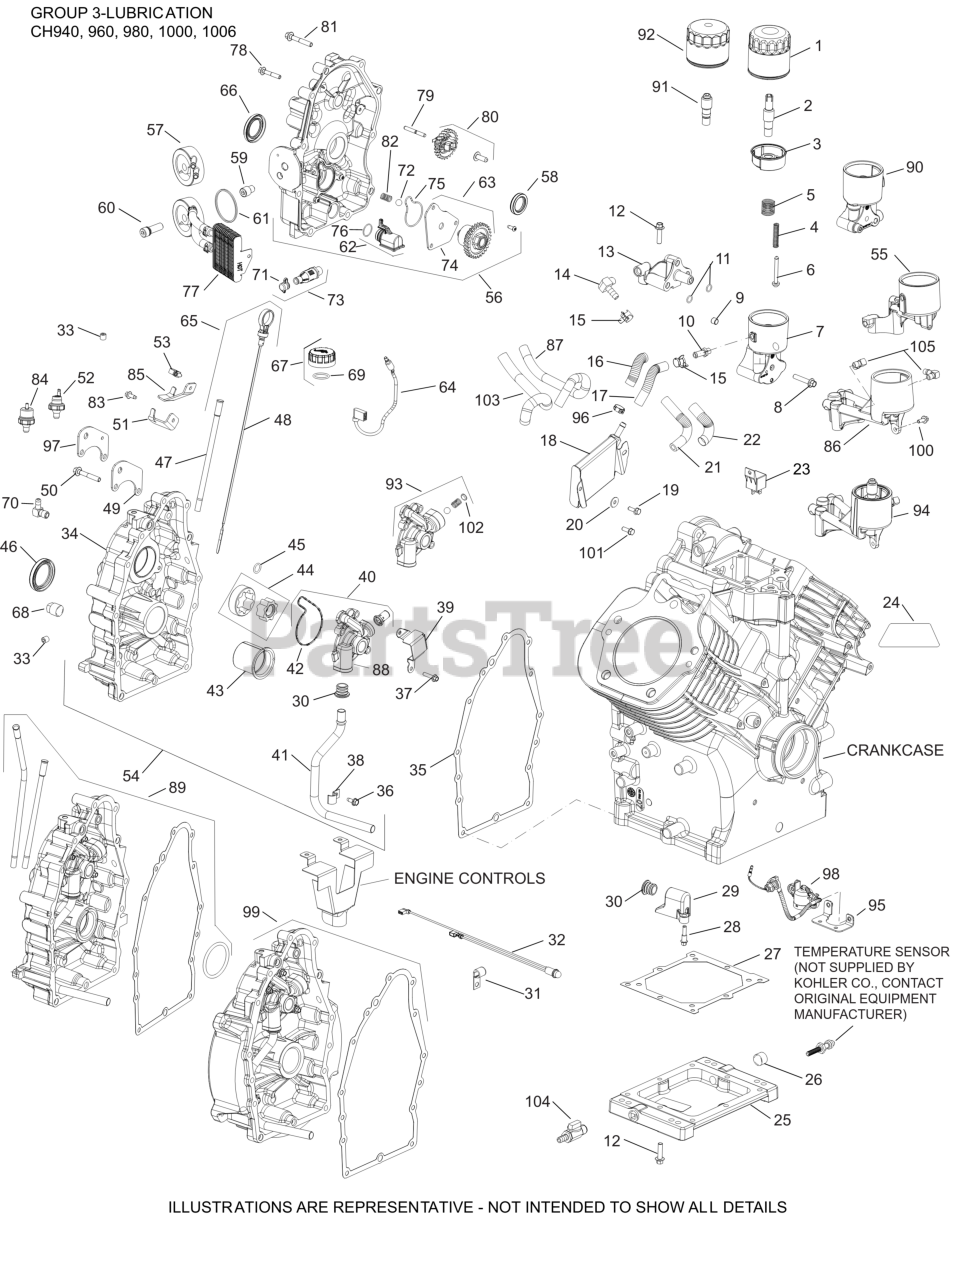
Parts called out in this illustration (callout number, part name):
1	OIL FILTER
3	CUP, OIL FILTER ASSEMBLY
4	SPRING, OIL FILTER VALVE
5	SPRING, OIL FILTER CUP
6	VALVE, OIL FILTER
11	O-RING, OIL PICK-UP
12	SCREW, FLG M8X1.25X30
15	SPRING CLAMP, HOSE
18	COOLER, OIL ASSEMBLY
20	WASHER, FLAT 1/4"
21	HOSE, OIL SUPPLY
22	SLEEVE, ANTI ABRASION-USE 25 431 12-S
25	OIL RESERVOIR
26	BUSHNG,REDCR 1/2"-1/8" NPT STL
27	GASKET, OIL RESERVOIR
28	SCREW, SHD THD FRM M6X.0X6.5
29	HOUSING, OIL PICK-UP ASSEMBLY
30	SEAL, PICK-UP TUBE
33	PLUG, CTSK PIPE 1/8"
35	GASKET, OIL PAN
36	SCREW, THREAD FORMING
37	SCREW, HEX FLANGE M6 X 1
41	TUBE, OIL PICK-UP
42	O-RING, OIL PUMP HOUSING
44	PUMP ASSEMBLY, OIL/GEROTOR
47	KIT, DIPSTICK TUBE
51	BRACKET, DIPSTICK TUBE
52	SWITCH, OIL PRESSURE
66	SEAL, OIL (LEFT-HAND HELIX, PTO)
72	PRESSURE RELIEF BALL
81	SCREW, HEX FLANGE
82	SPRING, COMPRESSION
83	SCREW, THREAD FORMING
86	HOUSING, HORIZ OIL FILTER-MACHINED
91	NIPPLE, OIL FILTER ASSEMBLY
93	ASSEMBLY, OIL PUMP HOUSING
94	HOUSING, OIL FILTER ASSEMBLY
96	CLAMP, HOSE OETIKER
99	Kit, Closure Plate
100	SCREW,HEX FLNGE
101	SCREW, HEX HEAD
102	PLUG, CUP
104	VALVE, OIL DRAIN
105	CONNECTOR, HOSE
NI	HOSE, OIL RETURN-DISCONTINUED
